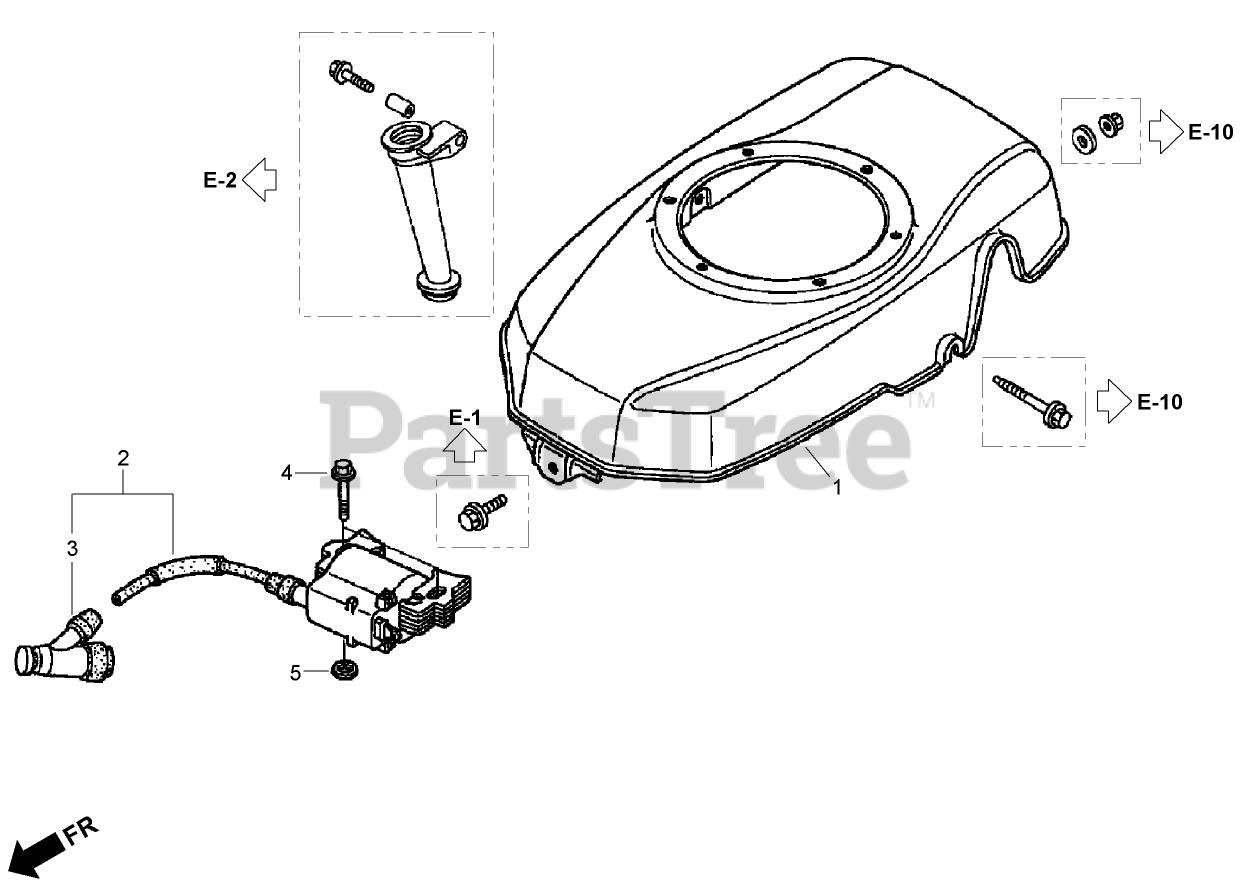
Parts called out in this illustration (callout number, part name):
1	COVER-FAN, R280 (POWER RED)
2	COVER-FAN (N H1) (BLACK)
3	IGNITION COIL ASM
3	NOISE SUPPRESSOR CAP ASM
4	BOLT-FLANGE (6X28) (C T200) (engine serial numbers starting at 6901761)
5	WASHER-PLAIN (6 mm)
